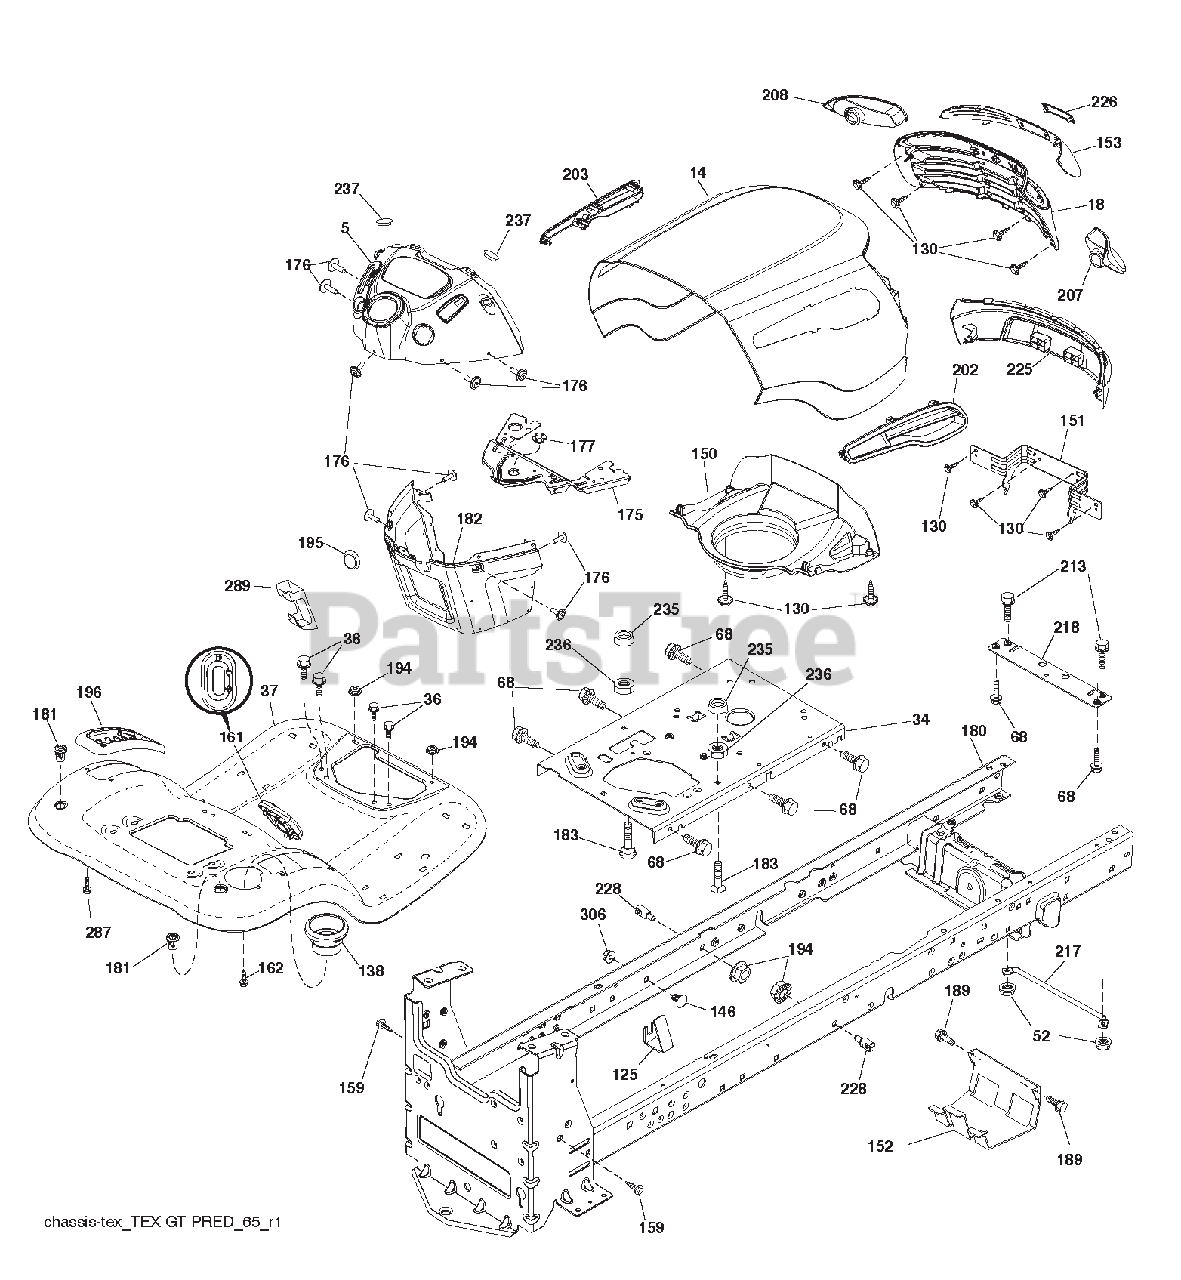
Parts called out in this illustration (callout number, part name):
5	DASH P/L TEX CABLE
18	GRILLE ELITE ARIENS BLACK
34	PLATE.ENGINE.WELDED.CHASSIS
36	SCREW.5/16-18X3/4.SMGML.TAP/R
37	FENDER TLT W/CPH W/FW
52	Nut, Hex, Crownlock 5/16-18
68	SCREW.THDROL.5/16-18 X 1/2TYTT
125	CLIP.FUEL.LINE
138	CUPHOLDER TL TEX 428
150	AIR DUCT
151	BRACKET.PIVOT
152	SHIELD.BROWNING.W/TEX
153	LENS.BAR
159	SCREW.HEXWSH THDR3/8-16X3/4.BL
161	WINDOW FUEL
162	SCREW.HEX.WSH.HI-LO.1/4X1/2UNC
175	CROSSMEMBER.LT
176	SCREW.#10-24X5/8.RND.QUDRX.GIM
177	BUSHING.STEERING.YT/GT
180	CHASS WLDMT TL 12 GA/2PC 18/22
181	BUSHING MNT FEND CRGO BLK TEX
182	DASH.LOWER.LT.CCS
183	BOLT.FIN.HEX.5/16-18 UNC X1-1/
189	SCREW.5/16-18X3/4.SMGML.TAP/BL
194	Nut, Lock Hex Flange 5/16-18 u
195	PLUG HOLE DASH TOWER
196	CONSLE.ASM.DECK.LFT.BL/RBT.TLT
202	VENT.LH
203	VENT.RH
207	BEZEL.RH
208	BEZEL.LH
213	BOLT.HEX.HD.1/4-20UNC X 3/4
217	ROD.PIVOT.HOOD
218	X-PIECE.HOOD.STOP.NON/STEALTH
226	ARIENS.LOGO.PLATE
228	STUD.FASTNER.W/'D'ANTI-ROTATIO
235	SPACER.FENDER
236	NUT.CENTER LOCK.5/16-18 UNC
237	PLUG.MOUNT.CARGO
278	X-PIECE HOOD
287	SCREW.HEX.WASHEAD.1/4-20 X 3/8
289	PLUG.CRUISE.CONTROL
306	Nut, Hex, Flangelock 3/8-16
